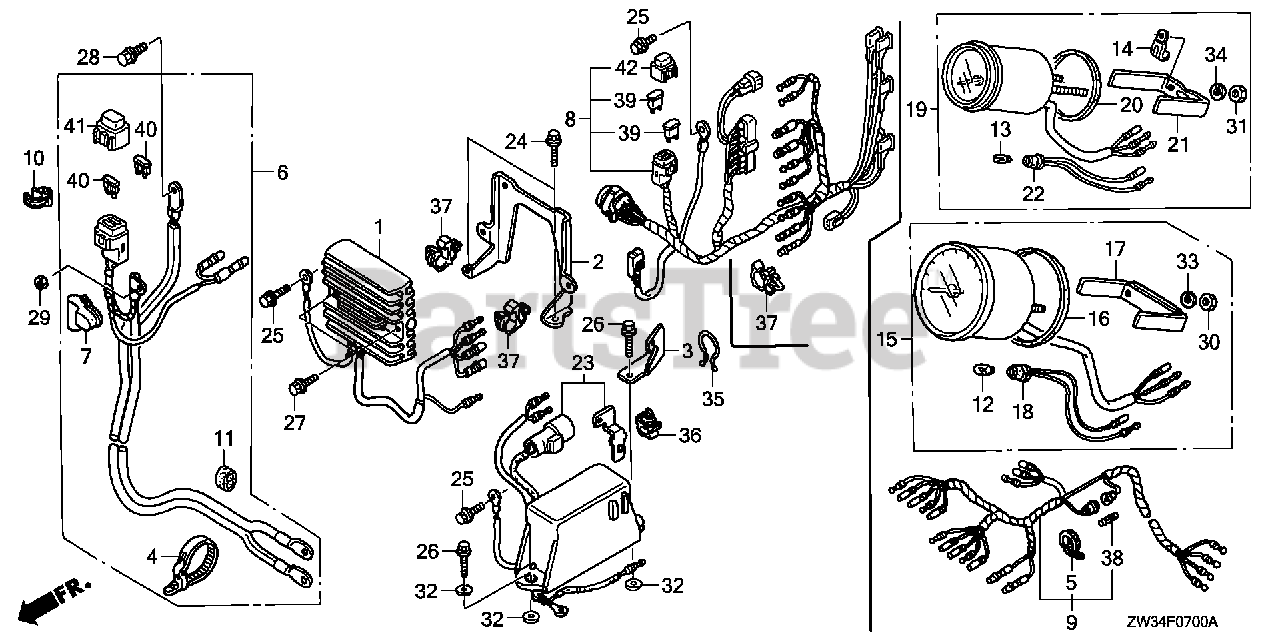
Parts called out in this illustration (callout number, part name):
1	RECTIFIER ASSY., REGULATOR (12A)
2	BRACKET, REGULATOR
3	BRACKET, HARNESS CLIP
4	BAND, WIRE
5	BAND B1, WIRE
6	CABLE ASSY., STARTER (PTT)
7	COVER, TERMINAL
8	CABLE ASSY., REMOTE CONTROL (A)
9	HARNESS ASSY., METER (A)
10	CLAMP, WIRE
11	CLAMP, IGNITION WIRE
23	RELAY ASSY., POWER TILT
24	BOLT, FLANGE (6X12) (CT200)
25	BOLT, FLANGE (6X12) (CT200)
26	BOLT, FLANGE (6X18) (CT200)
27	BOLT, FLANGE (6X20)
28	BOLT, FLANGE (8X12)
29	NUT, HEX. (6MM)
32	WASHER, PLAIN (6MM)
35	CLIP, PURSE LOCK
36	CLIP, CORD
37	CLIP, WIRE HARNESS
38	FUSE A (10A)
39	FUSE, BLADE (10A)
40	FUSE, BLADE (15A)
41	COVER ASSY., FUSE (15A)
42	COVER ASSY., FUSE (10A)
